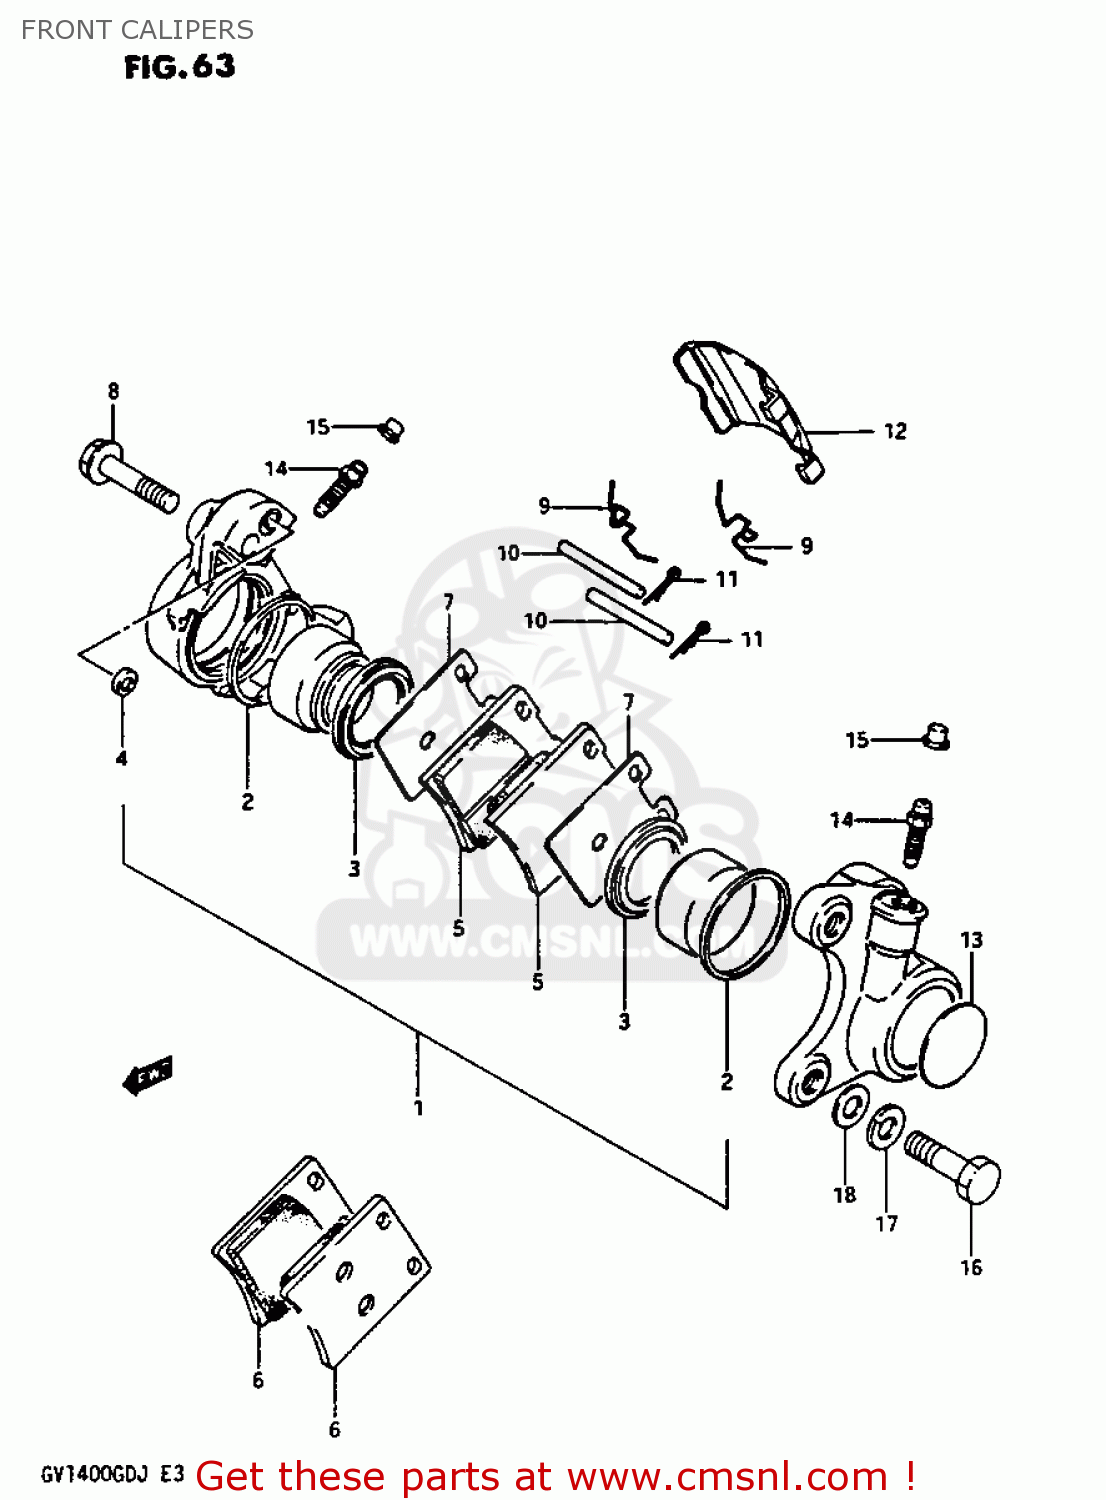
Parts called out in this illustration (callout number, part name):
1	PISTON SET
2	SEAL,FR CALIPE
3	BOOT,PISTON
4	SEAL,JOINT
5	PAD
6	PAD
7	SHIM,PAD
8	BOLT,HOUSING
9	SPRING
10	PIN,PAD
11	CLIP,PAD PIN
12	COVER
13	CAP,CALIPER
14	BLEEDER
15	CAP,BREATHER
16	BOLT(10X38)
17	WASHER,LOCK,10
18	WASHER
